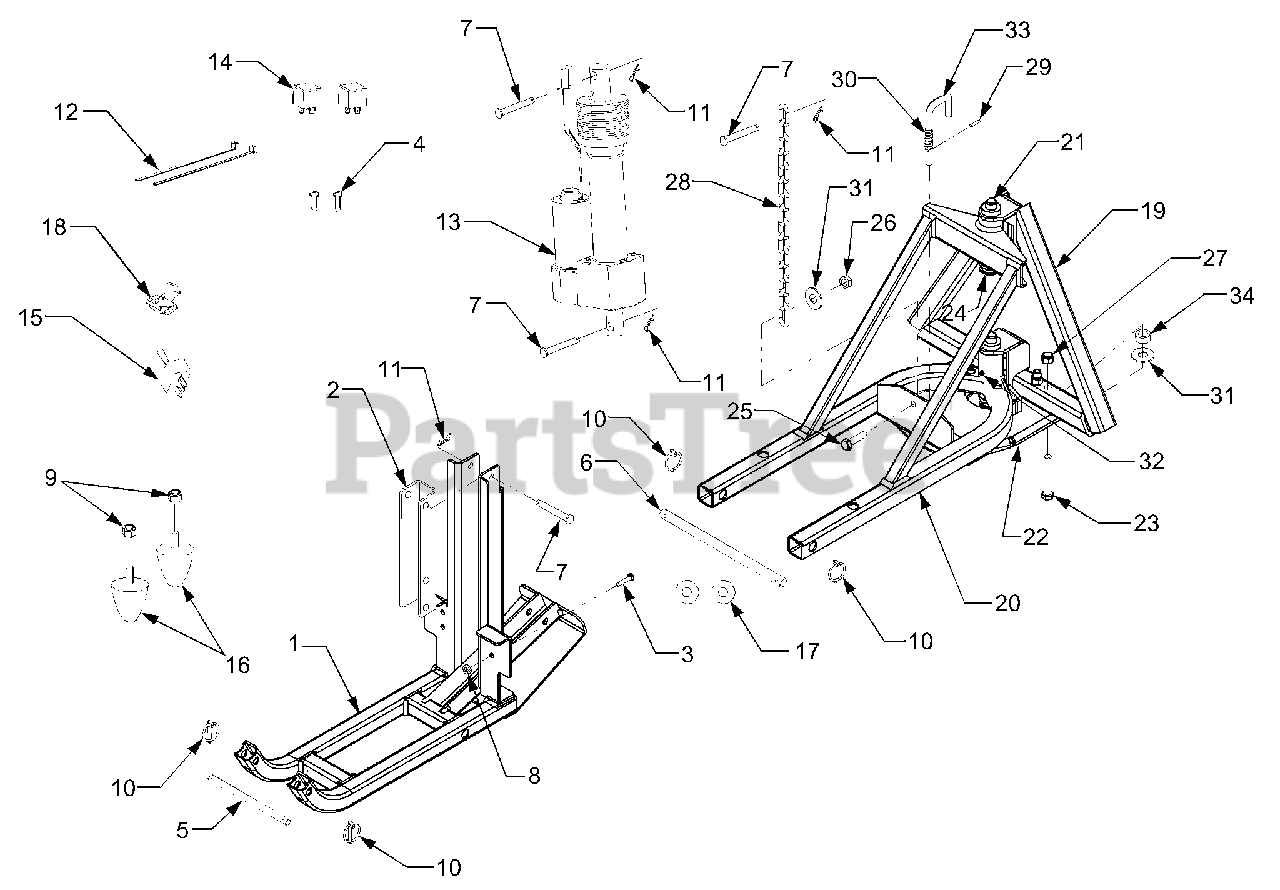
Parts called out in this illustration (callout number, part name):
1	Mounting Frame
2	Lift Bracket
3	Hex Cap Screw, 3/8-16 x 1.0 GR5
4	Self Tapping Screw
5	Mounting Rod, .625 x 8.625
6	Rod, .75 x 12.75
7	Clevis Pin, .5 Dia x 3.0
8	Hex Flange Lock Nut, 3/8-16
9	Hex Nylon Lock Nut, M10 x 1.25
10	Klik Pin
11	Internal Cotter Pin
12	Cable Tie
13	Electric Lift Cylinder
14	Relay, 12V
15	Toggle Switch
16	Rubber Bumper
17	Flat Washer
18	Splice Connector
19	Hitch 'A' Frame
20	Hitch Frame
21	Front Hitch Pin
24	Hex Wash. Hd. Tapp Screw, 5/16-18 x .75
25	Hex Cap Screw, 1/2-13 x 1.0 GR5
26	Hex Jam Nut, 1/2-13
27	Hex Nylon Lock Nut, 1/2-20
29	Spirol Pin
30	Compression Spring, .66 OD x 1.8
31	Flat Washer, .51 x 1.0 x .125
32	Lube Fitting, 3/16 Drive
33	Support Pin
34	Spacer, .628 x .875 x .5
